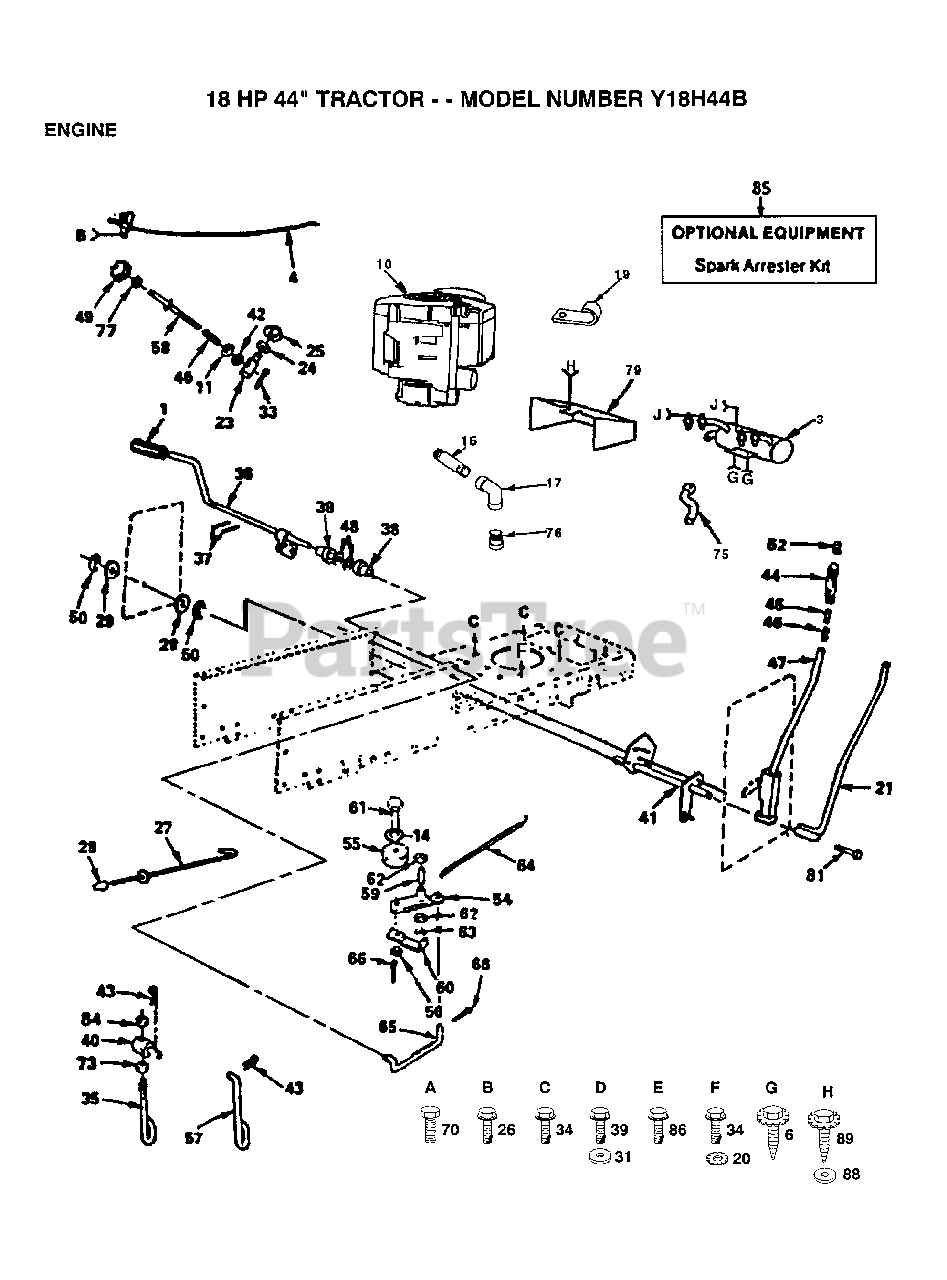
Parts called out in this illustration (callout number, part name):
1	PEDAL COVER T
4	"CONTROL,THROTTLE"
7	LOCKWASHER
8	WASHER PM
11	WASHER
14	WASHER
16	PIPE NIPPLE LT
17	ELBOW
19	MUFFLER CLAMP
20	LOCKWASHER
21	LEVER ROD LT
23	TRUNION LT
24	WASHER
25	KLIP RING
26	SCREW LT
27	BRAKE PARK ROD
28	PLUNGER CAP T
29	WASHER
34	SCREW LT
35	PIVOT PIN T
38	NYLON BEARING
41	LIFT SHAFT ASM
42	NUT T
44	GRIP
46	SPRING T
48	WASHER LT
50	E-RING
54	ARM IDLER
57	LIFT LINK LT
58	ROD LIFT LT
59	"LY, BEARING"
60	RETAIN BELT
62	WASHER LT
63	KLIP RING
64	"SPRING, RETURN LT"
65	"LINK, CLUTCH T"
66	COTTER PIN
73	NUT
74	SCREW
77	NUT
81	"BOLT,HEX"
